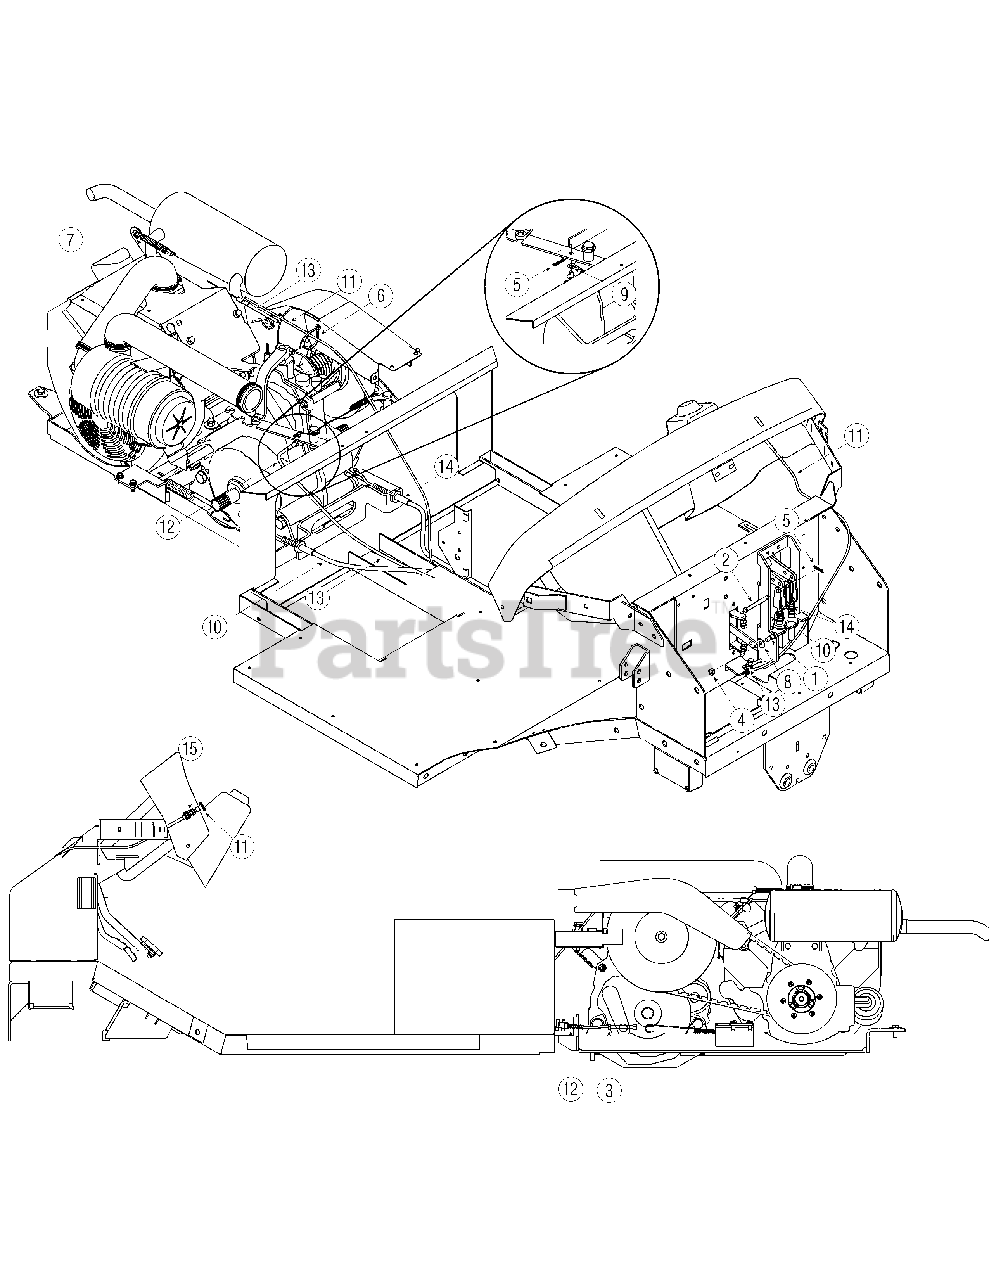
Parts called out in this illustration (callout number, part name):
1	Screw, Shoulder, .375 x .375
2	Pin, Clevis, 5/16 x 2.5
3	Nut, Jam, 5/16-24, Gr5
4	Nut, Hex Lock, 5/16-18
5	Pin, Cotter, .072 x 1.13
6	Cable Tie, Tree Mount
7	Extension Spring
8	Washer, .349 x .879 x .063
9	Washer, Spring, .317 x .879 x .063
10	Cable, Control, Brake
11	Cable, Control, Choke
12	Cable, Control, Clutch Brake
13	Cable, Control, Throttle
14	Cable, Control, Brake
15	Nut, Jam Lock 3/16-16, Gr5
